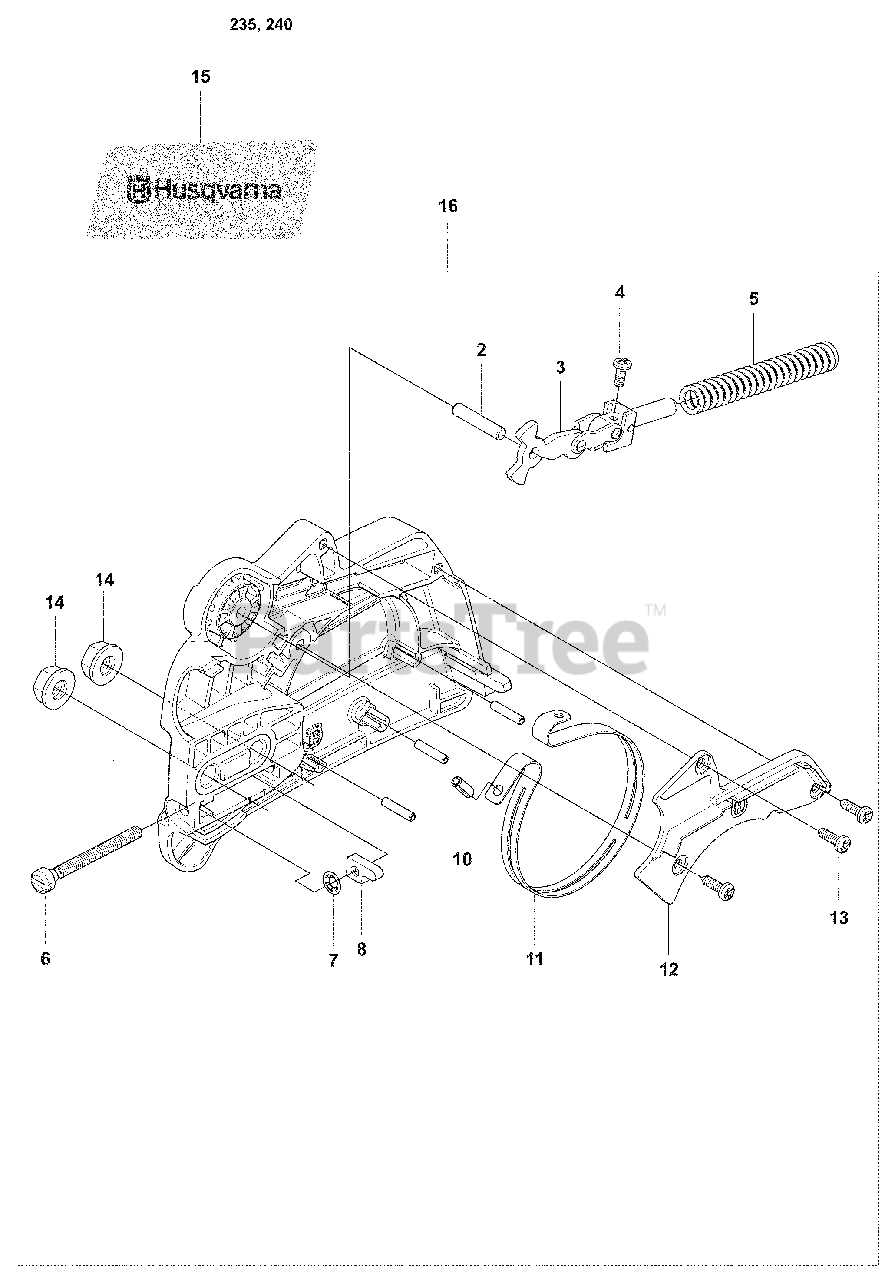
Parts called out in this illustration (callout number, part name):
2	PIN, DOWEL
3	ASSY, FRONT LINK
4	M3.83 X 1.81 X 9 PLASTITE
5	SPRING COMPRESSION
6	SCREW BAR ADJUSTING
7	RETAINER PUSH NUT
8	PIN BAR ADJUST
10	PIN, BAND RETAINER
11	BRAKE BAND
12	COVER, BRAKE BAND
13	SCP#6-19 X .437 .PL. PAN.
14	NUT, BAR MTG
16	CHAIN BRAKE ASS'Y FRT ADJ
